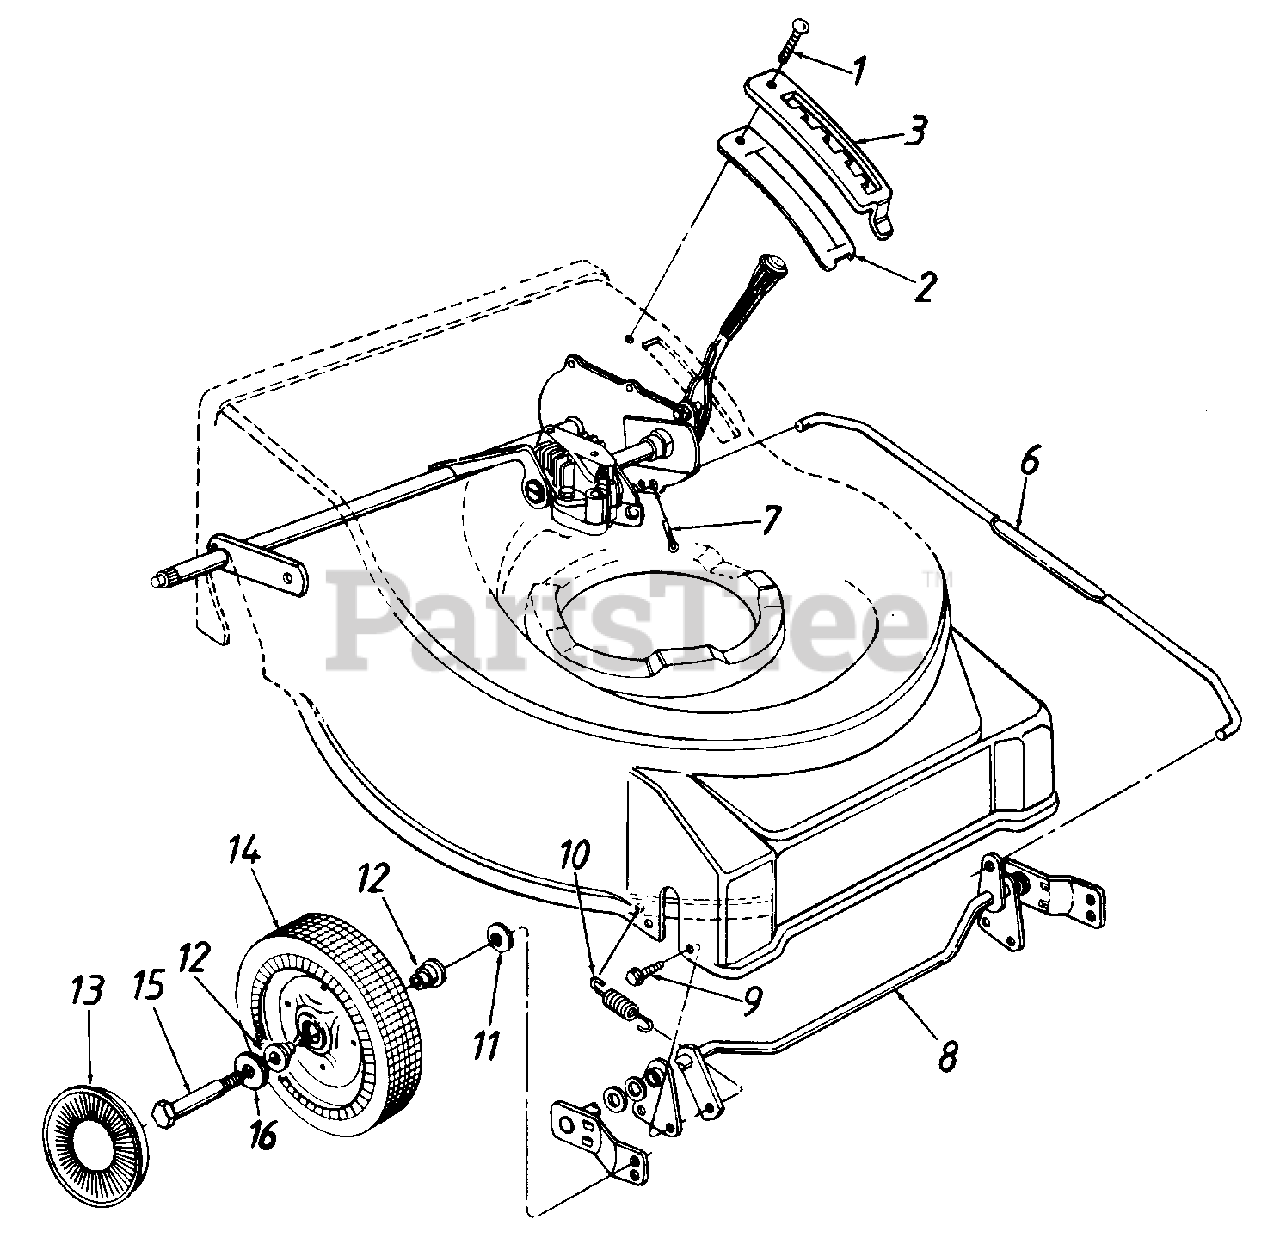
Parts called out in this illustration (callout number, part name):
1	Torx Mach. AB-Tap Scr. 1/4 x .62" Lg.
2	Height Adjustment Support
3	Height Adjustment Plate
6	Height Adj. Connecting Rod
7	Cotter Pin 3/32" Dia.
9	Hex L-Wash. Hd. AB-Tap Scr. 1/4 x .38" Lg.
10	Extension Spring 2.39" Lg.
11	Bell-Wash. .380" I.D. x .88"
12	Ball Bearing 1/2" I.D.
13	Hub Cap Gray (3-1/2" Dia.)
13	Hub Cap Gray (5-1/2" Dia.)
13	Hub Cap Beige (5-1/2" Dia.)
14	Wheel Ass'y. Comp. - Front
15	Shld. Bolt .498" Dia. x 1.45"
16	Wave Wash. .51" I.D. x .78"
